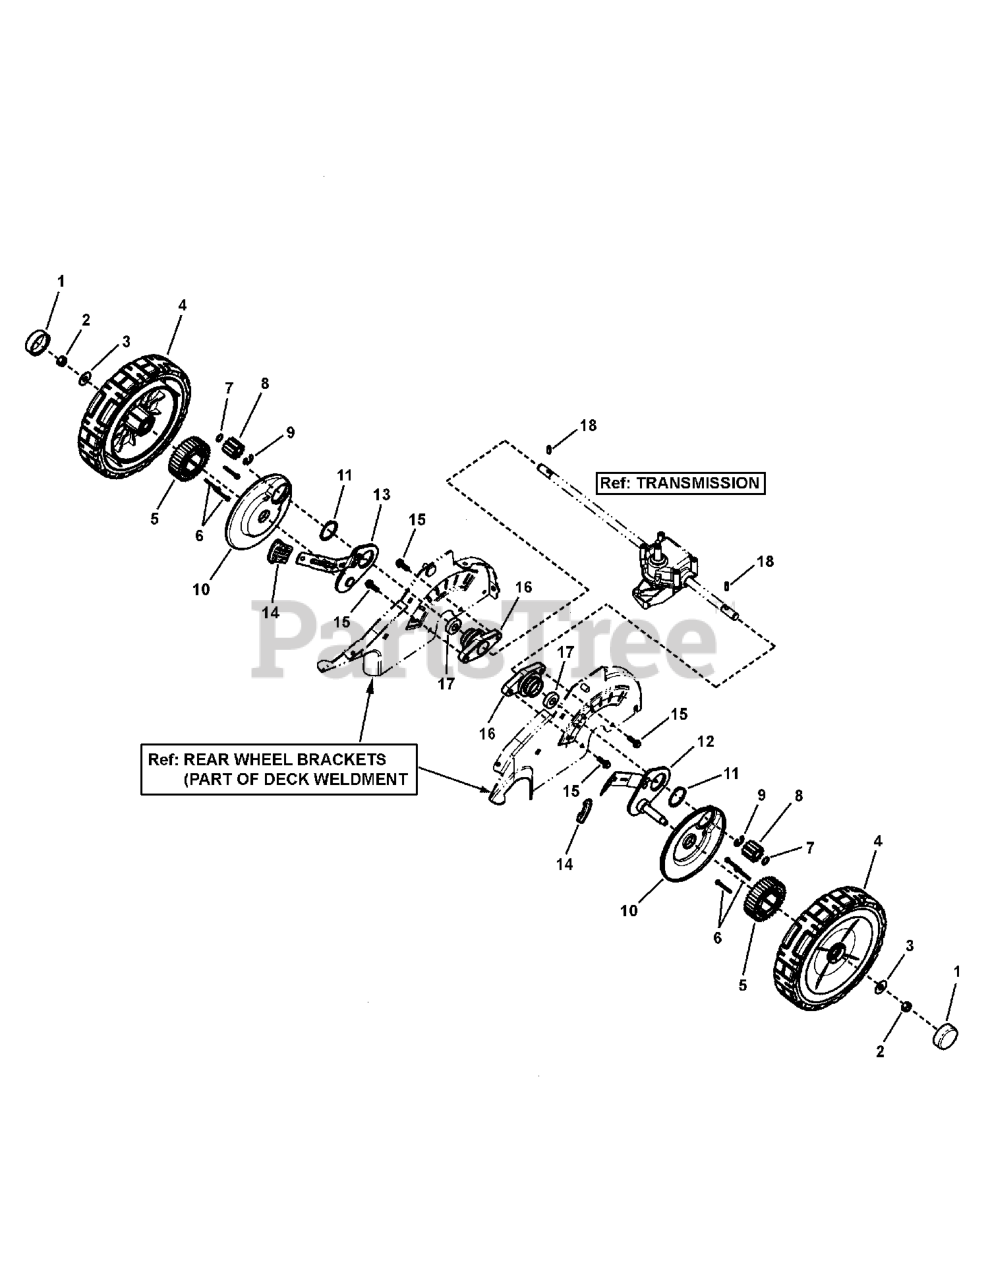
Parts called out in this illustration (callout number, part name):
1	HUBCAP, Round, Black
2	NUT, 3/8-16 Hex Center Lock, YZ
3	WASHER, 1" OD x .387 ID Flat
4	ASSEMBLY, Wheel, w/Bearing 9", Snapper Tread, Charcoal Gray
5	GEAR, External Wheel
6	SCREW, #8 x 1-1/4, Hex Washer Self-Tap (Hi-Lo)
7	RETAINING RING
8	GEAR, Pinion
9	RETAINING RING
10	SHIELD, Dust, 21" WBM, RD
11	SNAP RING, 1-3/8
12	ASSY, Axle Arm, Left Rear
13	ASSY, Axle Arm, Right Rear
14	GRIP, Height Latch, Black
15	HFLB, 1/4-20 X 3/4
16	HOUSING, Axle Bearing
17	BEARING, Ball
18	PIN, Axle
